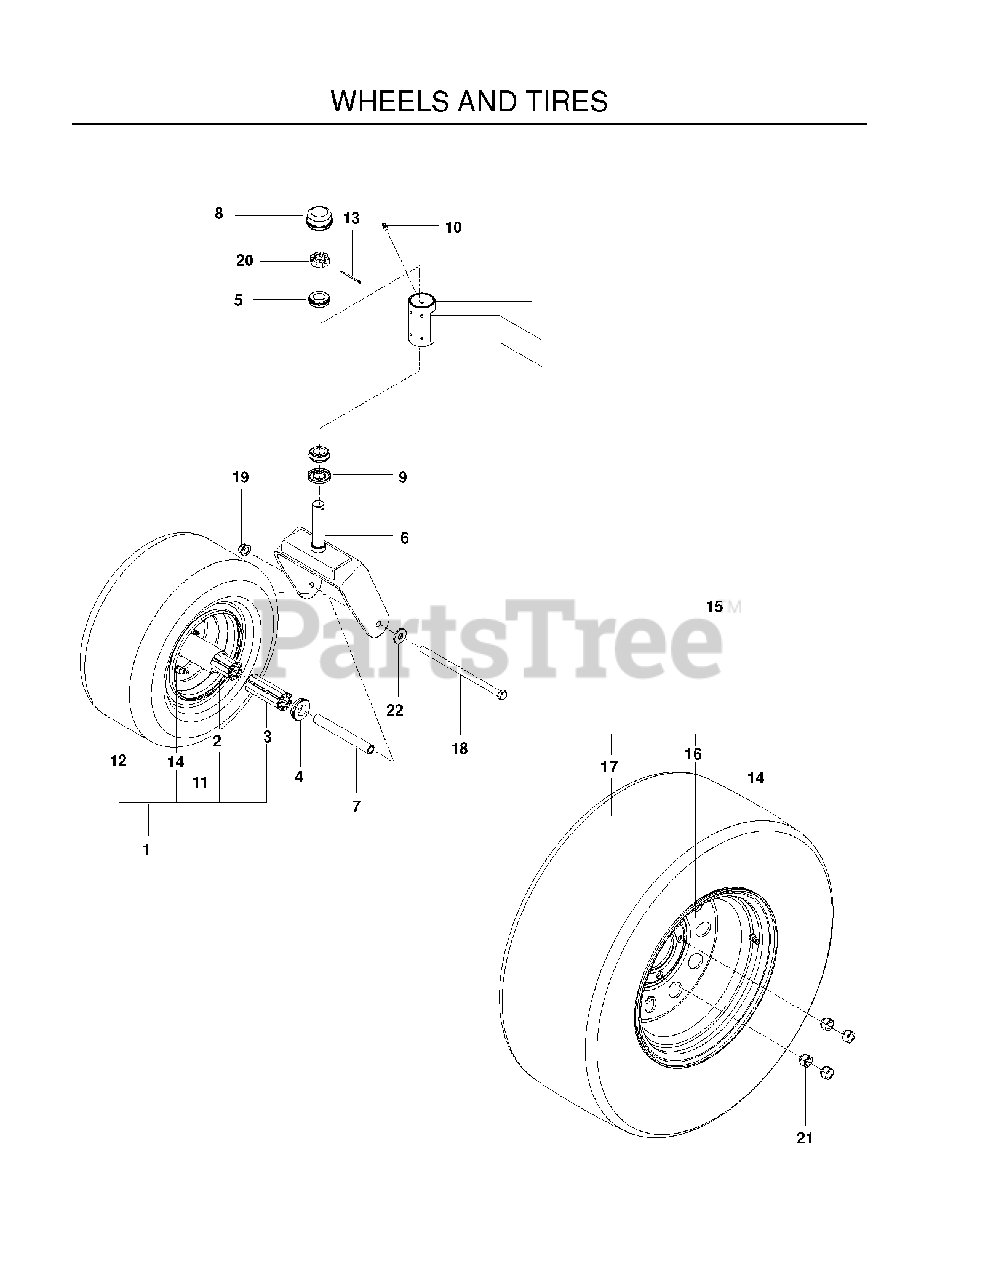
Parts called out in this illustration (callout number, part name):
1	ASM, TIRE
2	WHEEL, 6 X 4.50
3	ROLLER BEARING-CAGED 3 1/4'
4	BEARING RETAINER
5	TAPERED ROLLER BRG
6	YOKE, CASTER, BLUE
7	SPACER, PIVOT
8	GREASE CAP
11	ZERK
12	TIRE, 13 X 6.50 - 6, 4 PLY
14	VALVE STEM TR-412
15	WHEEL ASM, 23 X 10.5
16	RIM 2.5" NEG OFFSET 8.5" WIDE
17	TIRE - 23 X 10.5
18	HEX SCREW 1/2-13 X 9.5 GR5
19	NUT, 1/2-13 HEX FLG NYLOC ZD
20	NUT 1"C HEX SLOTTED
21	LUG NUT 1/2F
22	WASH USS FLAT 1/2
